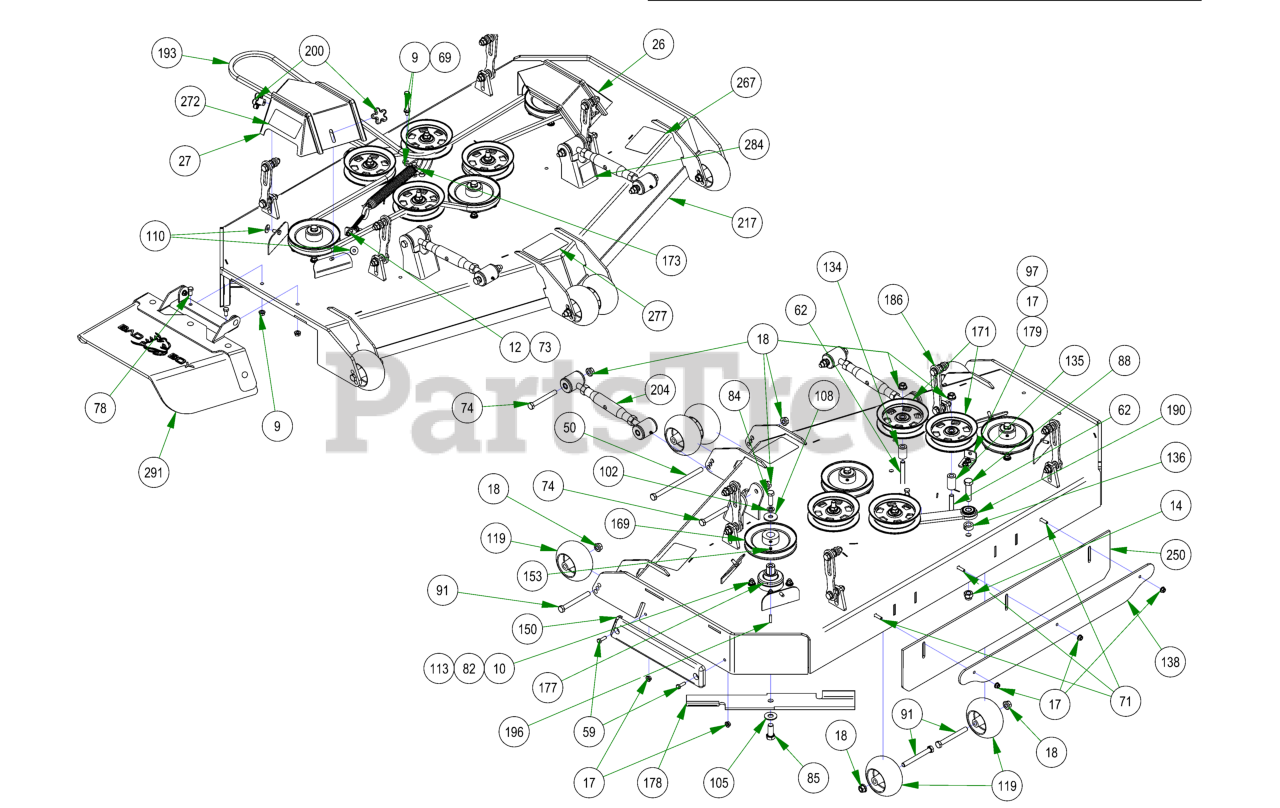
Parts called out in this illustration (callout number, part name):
9	3/8-16 HEX SERRATED FLANGE NUT HARD/ZINC
10	3/8-16 NYLON INSERT FLANGE LOCKNUT (GR.F) ZINC
12	3/8-16 HEX NUT ZINC
14	5/8-11 NYLON INSERT LOCKNUT ZINC
17	5/16-18 NYLON INSERT FLANGE LOCKNUT ZINC
18	1/2-13 NYLON INSERT FLANGE LOCKNUT ZINC
26	2019 61" Outlaw Gen2 Pulley Cover Left
27	2019 61" Outlaw Gen2 Pulley Cover Right
50	1/2-13 X 8 HEX CAP SCREW GR 5 ZINC
59	5/16-18 X 1 HEX CAP SCREW (GR.5) ZINC
62	1/2-13 X 3-1/2 HEX FLANGE BOLT (GR.8) ZINC
69	3/8-16 X 3 HEX CAP SCREW (GR.5) ZINC
71	5/16-18 X 1-1/4 CARRIAGE BOLT ZINC
73	4" 3/8-16 Eye Bolt
74	1/2-13 X 4 HEX CAP SCREW (GR.8) ZINC YELLOW
78	3/8-16 X 3/4 HEX CAP SCREW (GR.5) ZINC
82	3/8-16 X 1-1/2 HEX CAP SCREW (GR.5) ZINC
84	1/2-20 X 1-1/2 HEX CAP SCREW (GR.5) ZINC
85	5/8-18 X 1-1/2 HEX CAP SCREW (GR.8) ZINC YELLOW
88	5/8-11 X 2-1/2 HEX CAP SCREW (GR.5) ZINC
91	1/2-13 X 4-1/2 HEX CAP SCREW (GR.5) ZINC
97	5/16-18 X 7/8 CARRIAGE BOLT ZINC
102	1/2 SPLIT LOCKWASHER (GR.8) ZINC/YELLOW
105	5/8 USS FLAT WASHER (1-3/4" OD) GR.8 ZINC YELLOW
108	1/2 BELLEVILLE WASHER (1-5/8 OD X .140 THK) ZINC
110	.360 ID X .983 OD X .120 THICK FLAT WASHER NYLON BLACK
113	5/16 USS FLAT WASHER (7/8 OD) ZINC
119	2019 Deck Wheel
134	.502 ID X .750 OD X 1.500 Long Spacer
135	1 3/4" Pulley Spacer
136	5/8 SOLID SHAFT COLLAR (W/1 SET SCREW) ZINC
138	61 Bolt in Baffle Deck v2 Stripping Plate
150	REVISED TRIM BUMPER_20180226
153	5/16-24 X 1/4 SOCKET SET SCREW (CUP PT) PLAIN
169	6 1/4" Drive Pulley
171	5-3/4 Idler Pulley
173	2019 Outlaw Gen2 Deck Spring
177	OUTLAW SPINDLE ASSEMBLY
178	61 inch Fusion Blade
179	2019 Deck Eye Bolt Tab
186	Deck Hanger Assembly
190	2019 Renegade Deck Idler
193	Deck Belt for 61" Renegade
196	1/4 X 1 SQ MACHINERY KEY 1018 STL PLN
200	5/16" Knob
204	Turnbuckle
217	2019 Sloped 61" Deck
250	R Series Rubber For Deck
267	2018 61" Deck Decal
272	Danger Decal-Spindle/Discharge
277	2019 Renegade Deck Belt Route Decal
284	Deck Impact Patent Decal 9591803
291	2019 Outlaw Gen2 Chute Assembly
